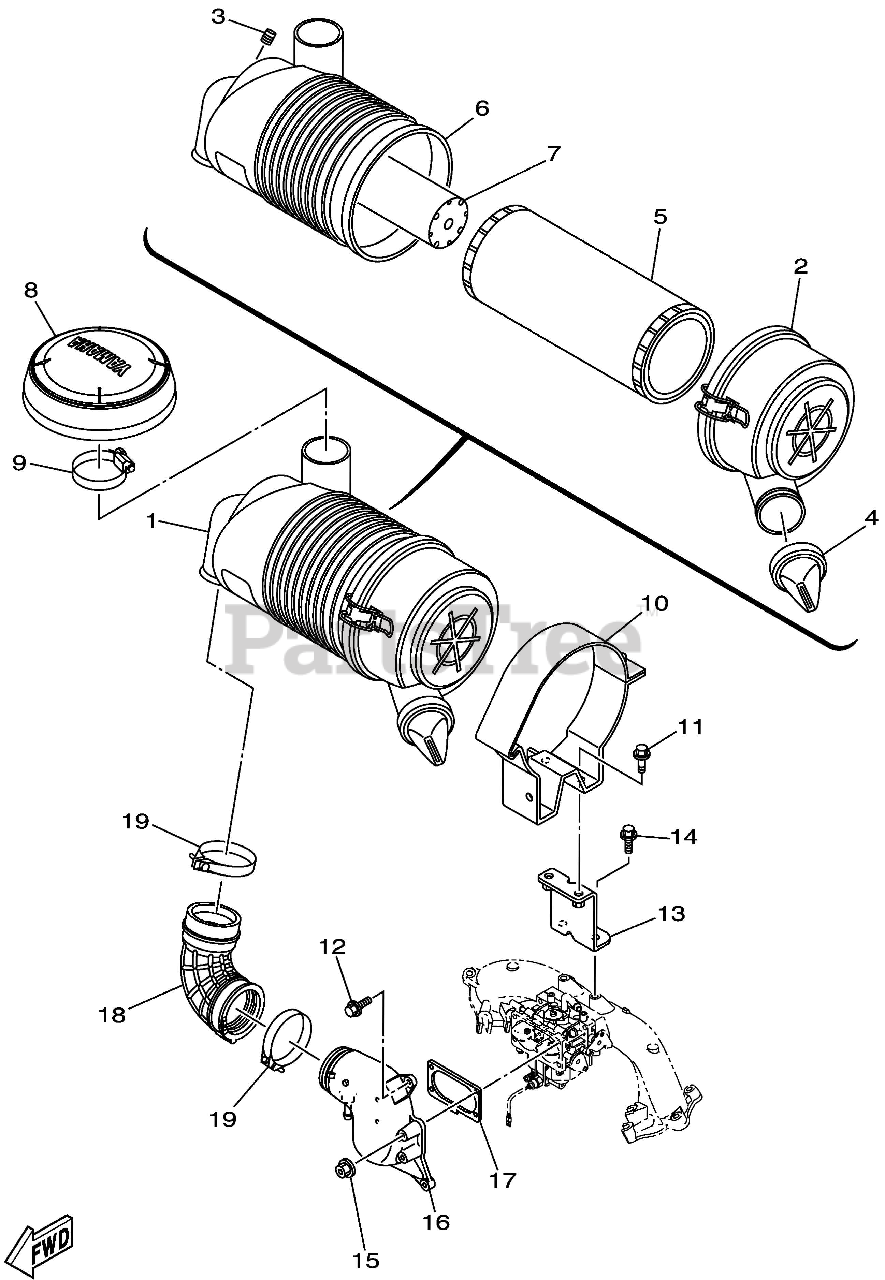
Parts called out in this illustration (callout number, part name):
1	AIR CLEANER ASSY.
2	CAP, CLEANER CASE 1
4	PLUG, BLIND
5	AIR FILTER (OUTER) - YAMAHA
6	CASE, AIR CLEANER 1
7	AIR FILTER (INNER) - YAMAHA
8	COVER, AIR 1
9	HOSE CLAMP ASSY
11	BOLT, FLANGE
12	BOLT, FLANGE
14	BOLT, FLANGE
15	NUT, FLANGE
16	JOINT, AIR CLEANER 1
17	GASKET, MANIFOLD 2
18	JOINT, AIR CLEANER 2
